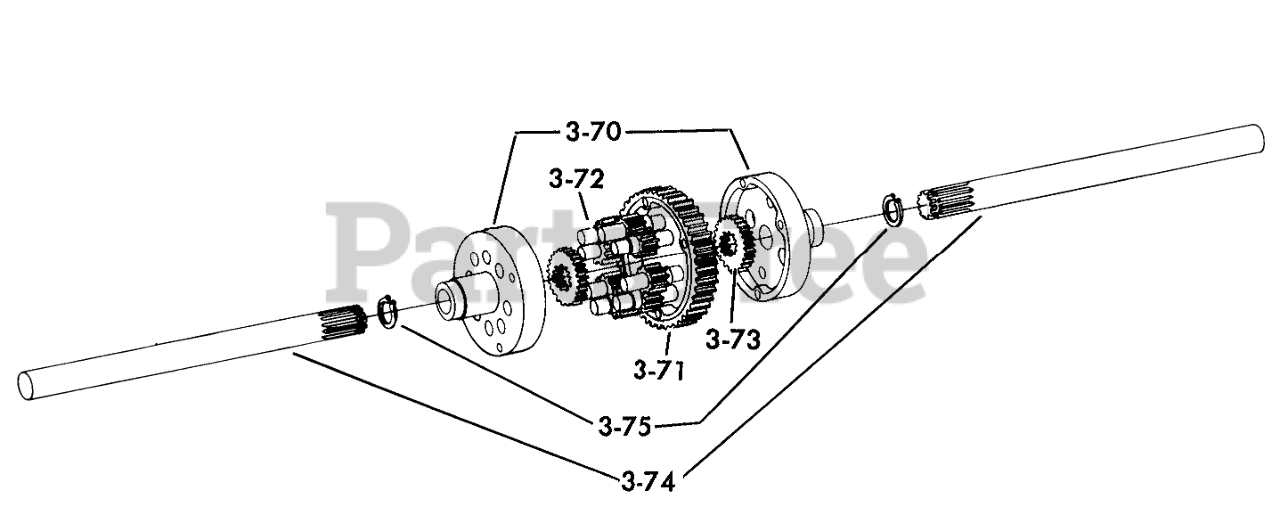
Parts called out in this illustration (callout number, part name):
3-70	End Cap
3-70	HHCS 5/16-18 X 3-1/2
3-70	Nut
3-71	Gear-Bull
3-72	GEAR-PINION, 11T
3-73	GEAR-AXLE DIFFERENTIAL
3-74	Axle
3-75	SNAP RING
